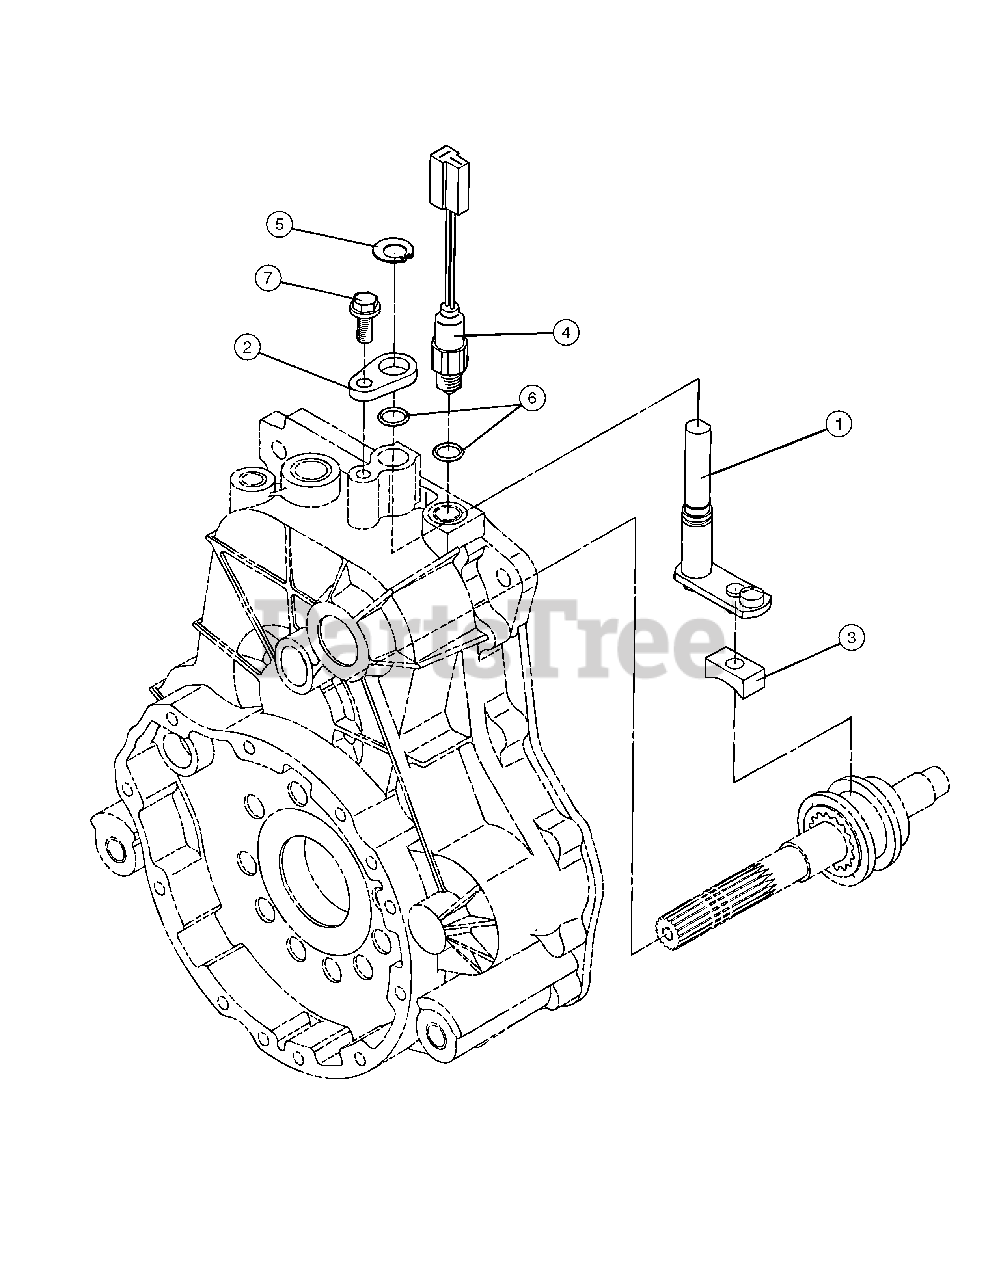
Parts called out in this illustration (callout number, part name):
2	Plate
5	Ring, 14
6	Packing, P 12.5
7	Tapping Screw, 8 x 20
